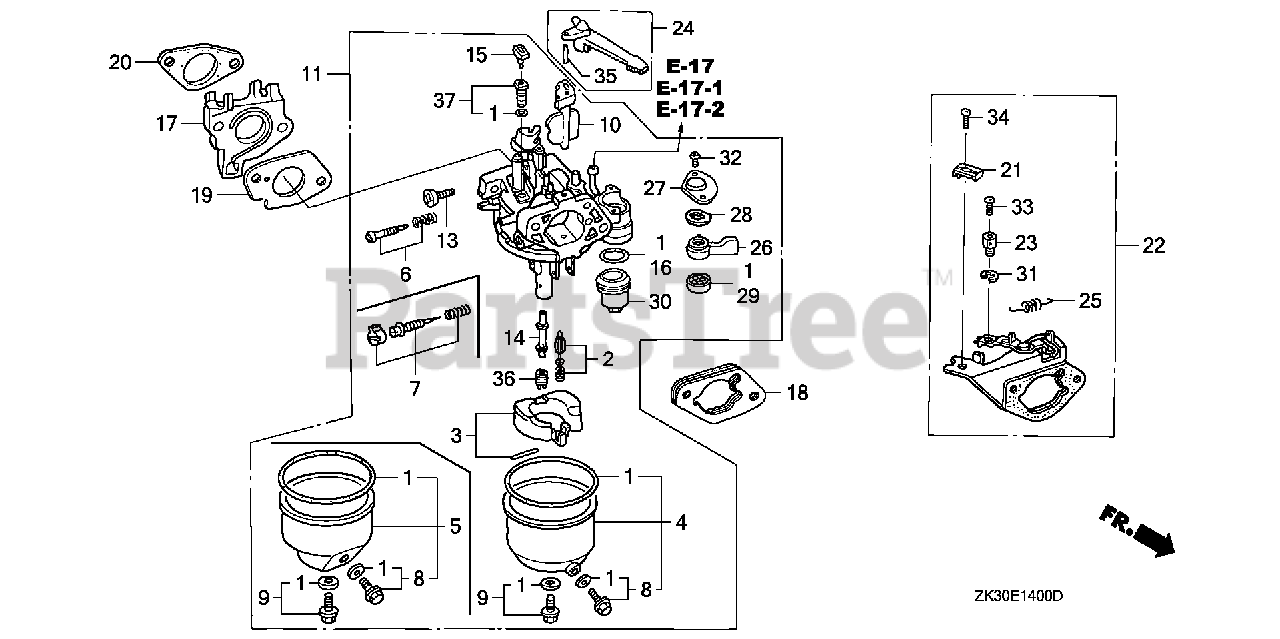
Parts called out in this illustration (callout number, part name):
1	GASKET SET (INCLUDES 16173-001-004)
2	VALVE SET, FLOAT
5	CHAMBER SET, FLOAT (CARBURETOR NO.)
7	SCREW SET, PILOT (CARBURETOR NO.)
8	SCREW SET, DRAIN
9	SCREW SET
10	CHOKE SET (CARBURETOR NO.)
11	CARBURETOR ASSY. (BE80C B)
13	SCREW, THROTTLE STOP
14	NOZZLE, MAIN (CARBURETOR NO.)
15	COLLAR, SETTING (CARBURETOR NO.)
16	GASKET, FUEL STRAINER CUP
17	INSULATOR, CARBURETOR
18	SPACER, CARBURETOR
19	GASKET, CARBURETOR
20	GASKET, INSULATOR
24	LEVER, CHOKE (STD)
26	LEVER, PETCOCK (CARBURETOR NO.)
27	PLATE, LEVER SETTING (CARBURETOR NO.)
28	SPRING, PETCOCK LEVER
29	GASKET, PETCOCK
30	CUP, FUEL STRAINER
32	SCREW, PAN (3X6)
35	PIN, SPRING (2X12)
36	JET, MAIN (#95) (CARBURETOR NO.)
36	JET, MAIN (#98) (CARBURETOR NO.)
36	JET, MAIN (#100) (CARBURETOR NO.)
37	JET SET, PILOT (#35) (CARBURETOR NO.)
